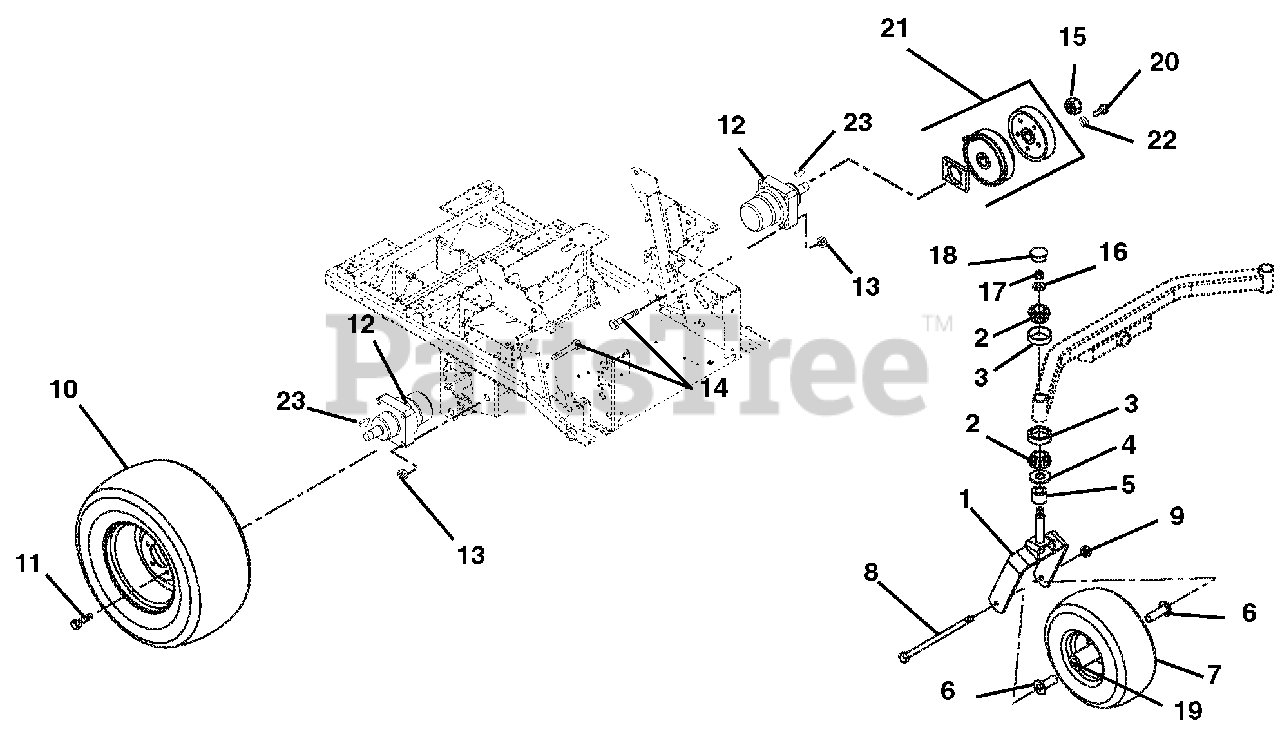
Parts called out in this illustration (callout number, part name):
1	FORK - FRONT
2	BRG, CONE W/ GREASE
3	BRG-CUP1.980X.420
4	BEARING SEAL 1.5 X 2 X .18
5	SPACER 1.005X1.5075X.375
6	SPACER, FRONT WHEEL
7	TIRE/WHEEL ASSY, 15X6.00-6
8	@BLT-HEX .50-13X9.00 GR5 YWZC
9	@NUT-LK-CTR .50-13 YWZC
10	TIRE/WHEEL ASSY, 24X11.50-12
11	BLT-LUG .50-20X1.38 YWZC
12	WHEEL MOTOR, 18E (CCW)
13	@NUT-LK-TOP-FLG .50-13 YWZC
14	BLT-HEX .50-13X2.75 YZ GR8
15	NUT-LK-JAM-PTCH 1.00-20
16	@WSHR-FL-STL.812X1.50X.135YWZC
17	NUT-JAM CTRLK .75-16 YWZC
18	CAP,DUST
19	BRG, 25MM ID X 52MM OD X 15MM
20	BLT-HEX .31-18X1.50 GR8YZ EP30
21	KIT, BRAKE SERVICE (1-SIDE)
22	@WSHR-LK .31X.078 REG YWZC
23	KEY-WDRF .31X1.00 SFT #B
